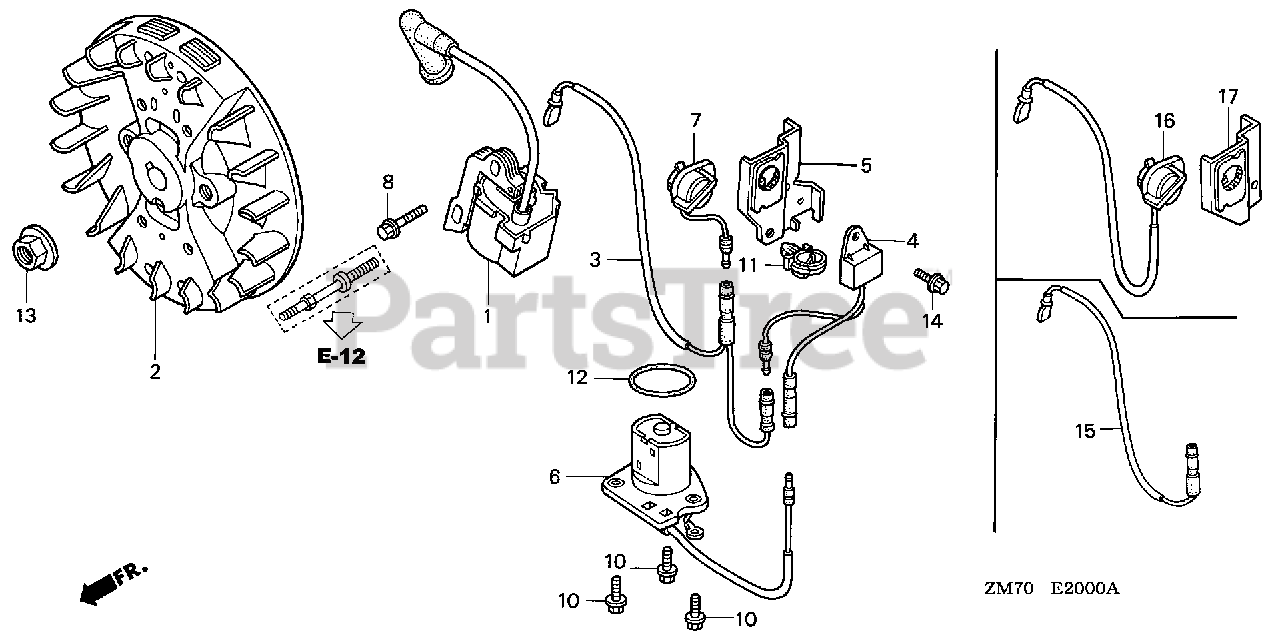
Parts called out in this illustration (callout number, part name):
1	COIL ASSY., IGNITION
8	BOLT, FLANGE (5X20)
13	NUT, FLANGE (10MM)
15	WIRE, STOP SWITCH
